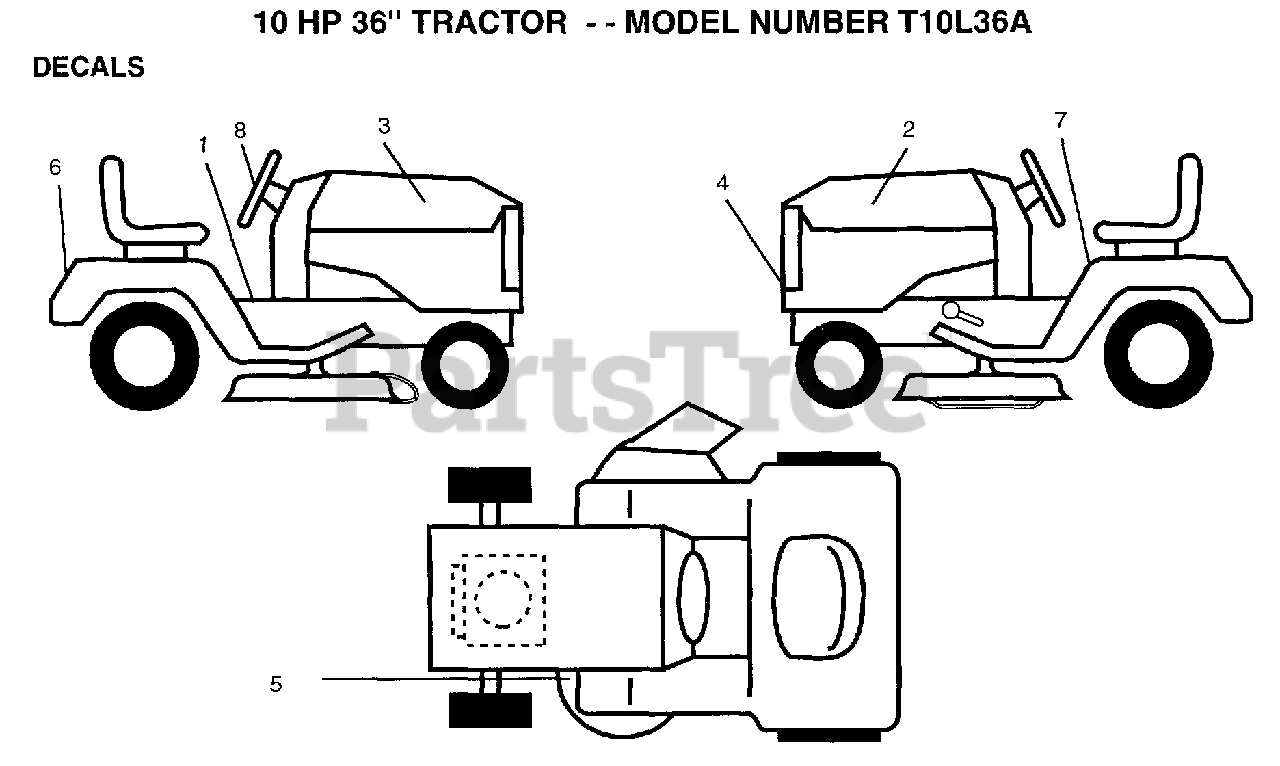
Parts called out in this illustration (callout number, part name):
1	DECAL.INST.OPER
2	DECAL.HD.LH.10HP
3	DECAL.HD.RH.10HP
5	DECAL.V.BELT
6	DECAL.FENDER.COOP
7	DECAL
